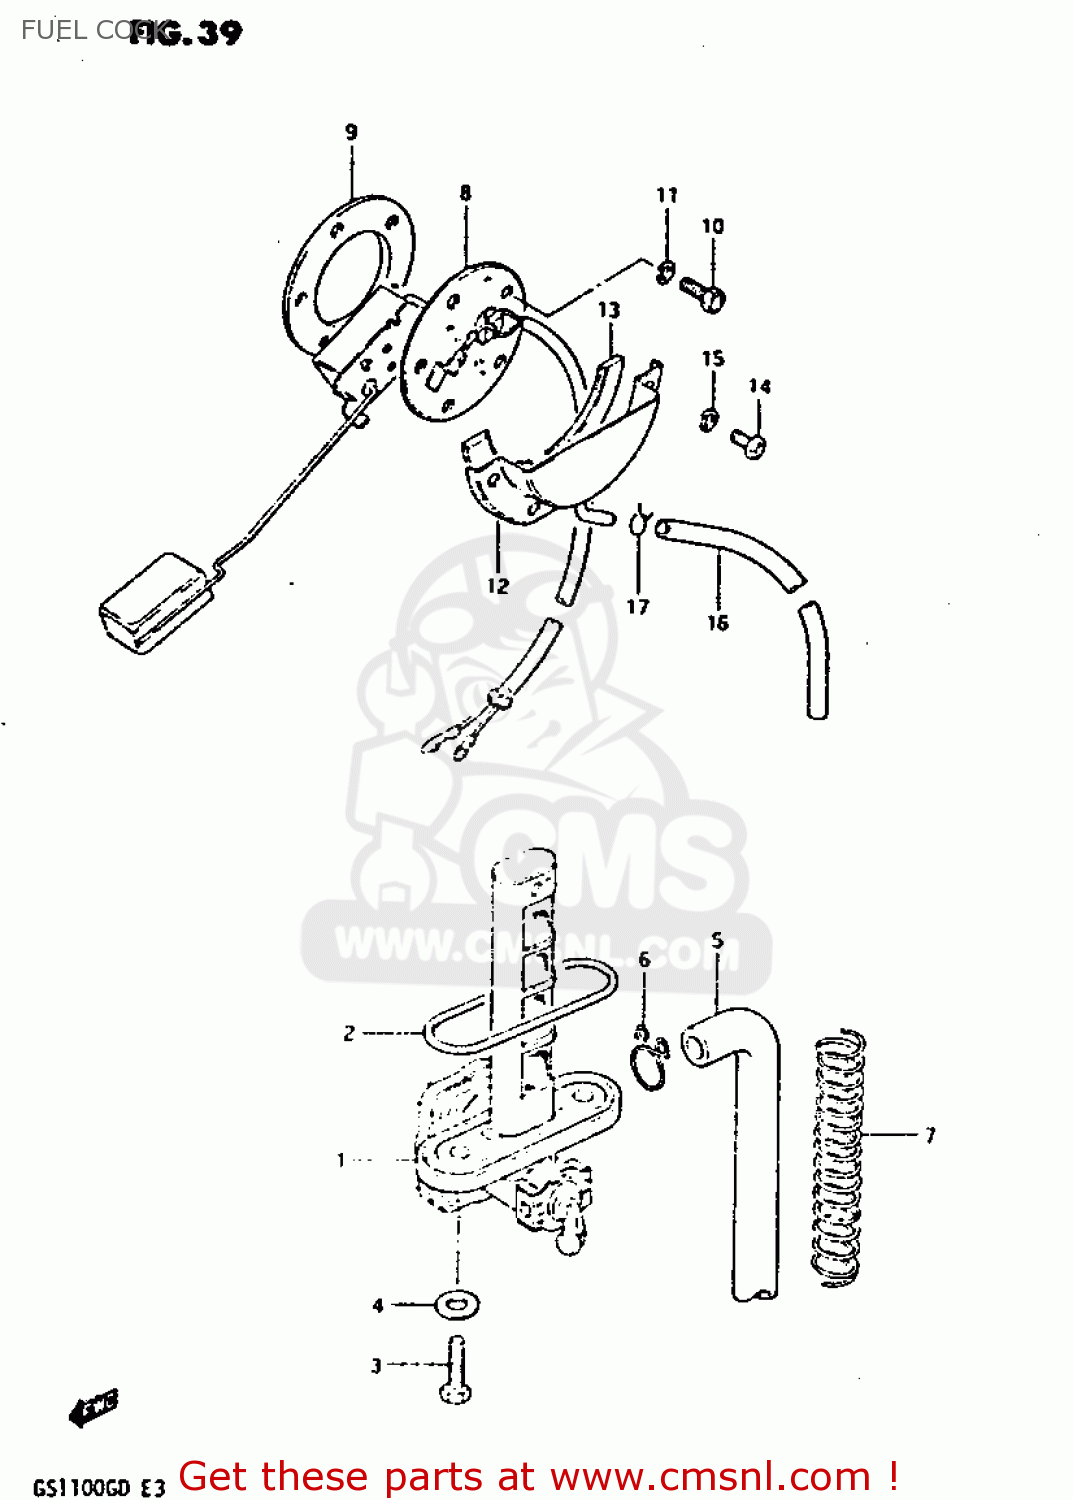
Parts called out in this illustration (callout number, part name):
1	COCK ASSY,FUEL
2	O RING
3	BOLT(6X20)
4	GASKET(5.8X13X1.2) (NAS)
5	HOSE(7X10.2X2000)
6	CLIP
7	SPRING
8	GAUGE ASSEMBLY,FUEL LEVEL
9	GASKET,FUEL LEVEL GAUGE (NAS)
10	BOLT 5X10
11	LOCK WASHER
12	PLATE,FUEL DRAIN
13	GASKET (NAS)
14	SCREW
15	LOCK WASHER
16	HOSE
17	CLIP
